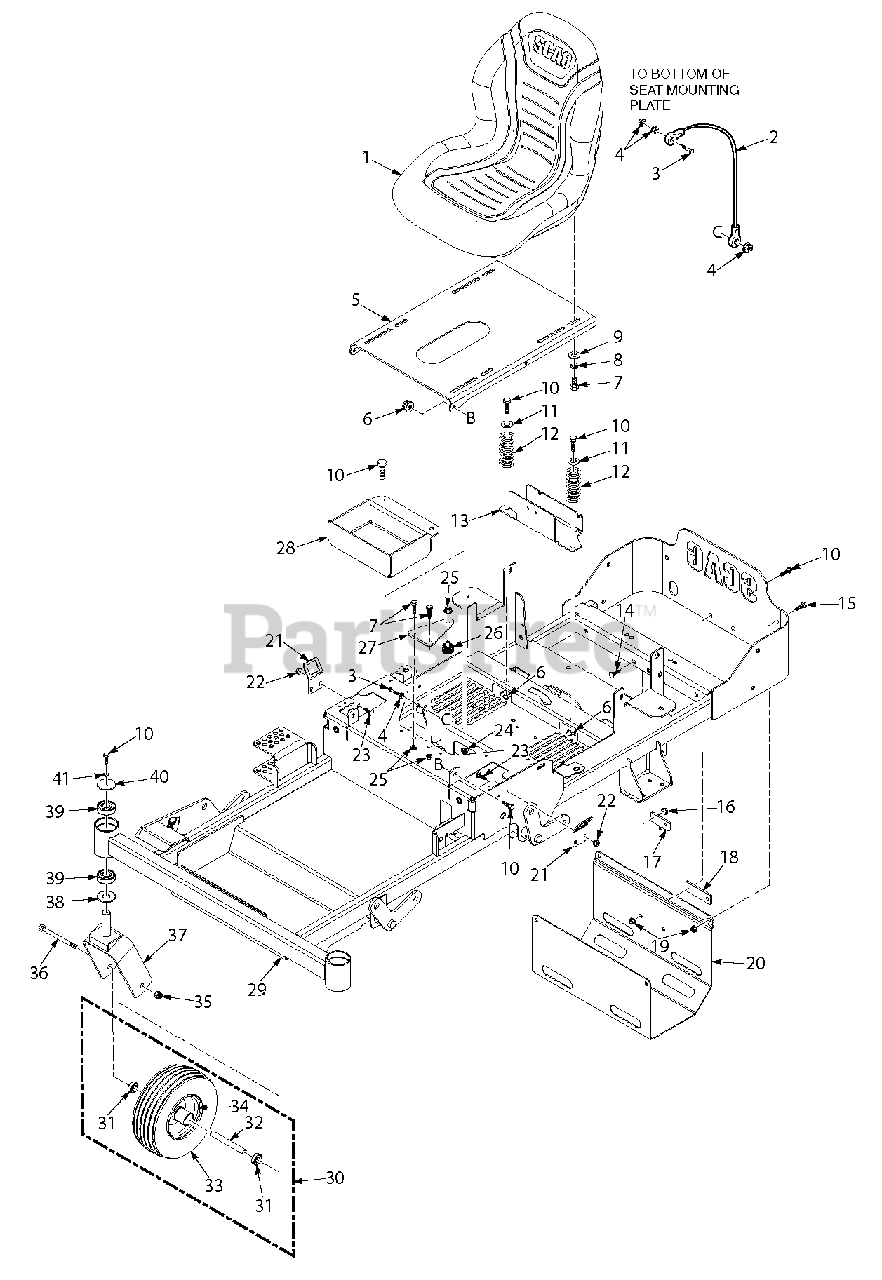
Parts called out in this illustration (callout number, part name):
1	Seat, SZL
2	Cable, Seat Stop
3	Bolt, Hex Head 1/4-20 x 1-1/4"
4	Nut, 1/4-20 Serrated Flange
5	Seat-Plate W/Decal
6	Threaded Insert, 3/8-16
7	Bolt, Hex Head 5/16-18 x 3/4"
8	Lockwasher, 5/16"
9	Flatwasher, 5/16-.375 x .875 x .083
10	Bolt, Hex Head 3/8-16 x 1"
11	Flatwasher, 3/8-.391 x .938 x .105
12	Spring, Seat
13	Seat Stop
14	Bolt, Hex Head 5/8-11 x 1-1/2"
15	Bolt, Hex Head 3/8-16 x 3/4"
16	Nut, 5/16-18 Elastic Stop
17	Plate, Anti-Rotation
18	Plate, Spacer
19	Nut, 3/8-16 Serrated Flange
20	Skid Plate, SZL-36
21	Bracket, Switch
22	Nut, 1/4-20 Flange Elastic Stop
23	Bolt, Carriage 1/4-20 x 3/4"
24	Threaded Insert, 3/8-16
25	Threaded Insert, 5/16-18
26	Bumper, Rubber
27	Battery Hold Down
28	Battery Box
29	Frame Assembly, SZL-36
30	Caster Wheel Assembly
31	Bearing
32	Spacer, Wheel Bearings
33	Tire, 11 x 4
34	Rim Assembly
35	Nut, 1/2-13 Elastic Stop
36	Bolt, Hex Head 1/2-13 x 6-1/2"
37	Bearing
38	Spacer, Yoke
39	Bearing
40	Flatwasher, 3/8-.406 x 2.25 x .188
41	Lockwasher, 3/8"
